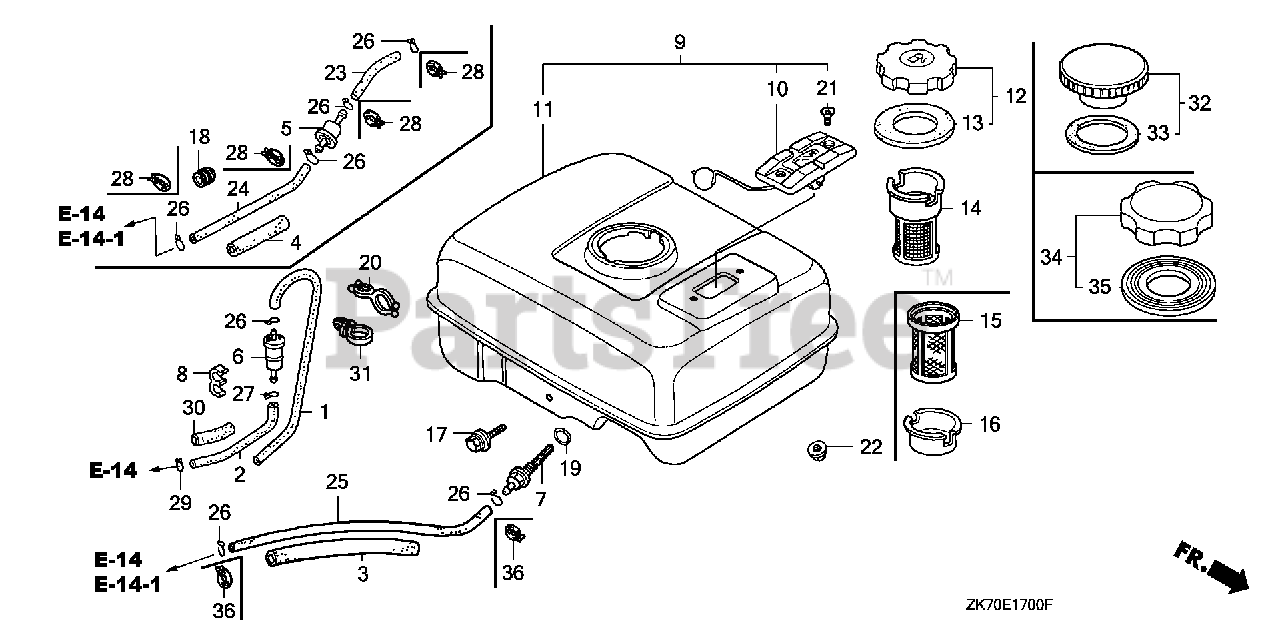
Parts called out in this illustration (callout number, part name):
3	RUBBER, SUPPORTER (107MM)
7	JOINT, FUEL TANK (NOT AVAILABLE)
7	JOINT, FUEL TANK
11	TANK, FUEL *NH31* (MCKINLEY WHITE)
14	FILTER, FUEL
17	BOLT, FLANGE (6X29)
19	O-RING (14MM) (ARAI)
19	O-RING (14MM) (NOK)
22	NUT, FLANGE (6MM)
25	BULK HOSE, FUEL (4.5X3000) (4.5X140)
26	CLIP, TUBE (B8)
34	CAP, FUEL FILLER (CHROME PLATED)
35	GASKET, FUEL FILLER CAP (39X62X3) (TOUYOUSYA)
